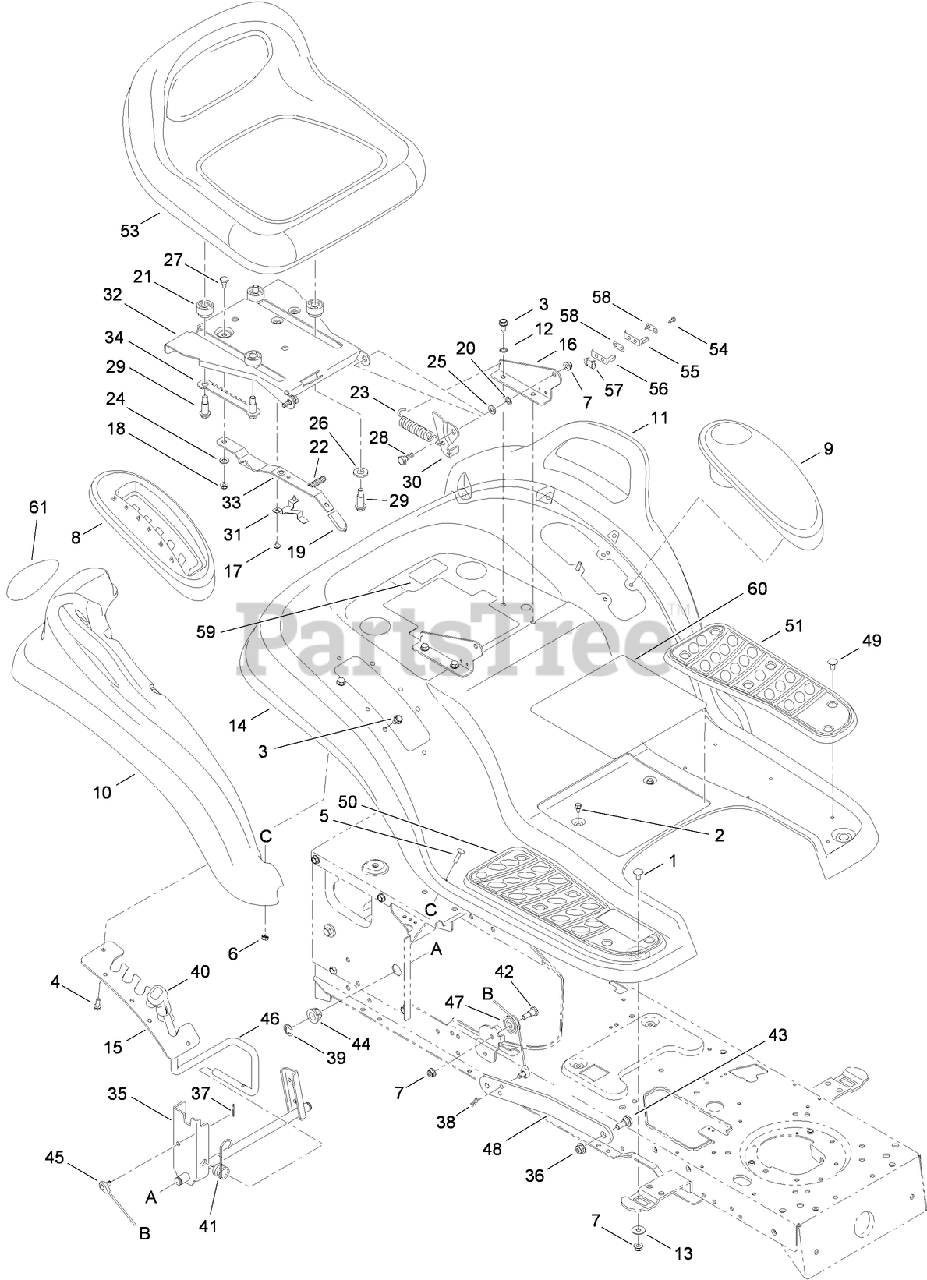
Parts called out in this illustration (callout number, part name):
1	BOLT-CARR
2	SCREW-HWHTF
3	SCREW-TAP
4	SCREW-TAP
5	SCREW-CARR
6	NUT-SEMS
7	NUT-LOCK, FLANGE
8	COVER-LEVER, LIFT
9	COVER (W/CUP HOLDER)
10	FLARE-FENDER, RH
11	FLARE-FENDER, LH
12	WASHER-LOCK, EXTERNAL
13	WASHER-FLAT
14	FENDER
15	BRACKET-ADJUSTING, LIFT
16	BRACKET-MOUNT, SEAT
17	SCREW-HH, TAP
18	NUT-LOCK, FLANGE
19	GRIP-ADJUSTER, SEAT
20	NUT-PUSH
21	SPACER-ADJUST, SEAT
22	SPRING-COMPRESSION
23	SPRING-EXTENSION
24	WASHER-BELL
25	WASHER-BELL
26	WASHER-FLAT
27	BOLT-SHOULDER
28	BOLT-SHOULDER
29	BOLT-SHOULDER
30	BRACKET-LIFT, LH
31	STOP-ADJUST, SEAT
32	BRACKET-PIVOT, SEAT
33	LEVER-ADJUST, SEAT
34	SELECTOR-ADJUST, SEAT
35	LIFT SHAFT ASM
36	NUT-LOCK, FLANGE
37	PIN-COTTER
38	PIN-COTTER
39	RING-E
40	GRIP-HANDLE
41	SPRING-TORSION
42	BOLT-SHOULDER
43	BOLT-SHOULDER
44	BEARING-FLANGE
45	CABLE-LIFT
46	HANDLE-LIFT
47	PULLEY-ROLLER
48	ARM-LIFT
49	CLIP-RATCHET, FASTENER
50	PAD-FOOT, RH
51	PAD-FOOT, LH
53	SEAT-MEDIUM BACK
54	SCREW-HWHTF
55	SWITCH-SPRING
56	SWITCH-SPRING, INNER
57	PLATE-BOSS, INSULATOR
58	PLATE-INSULATOR
59	DECAL-SERVICE
60	DECAL-INSTRUCTIONS, OPERATOR
61	REFLECTOR
